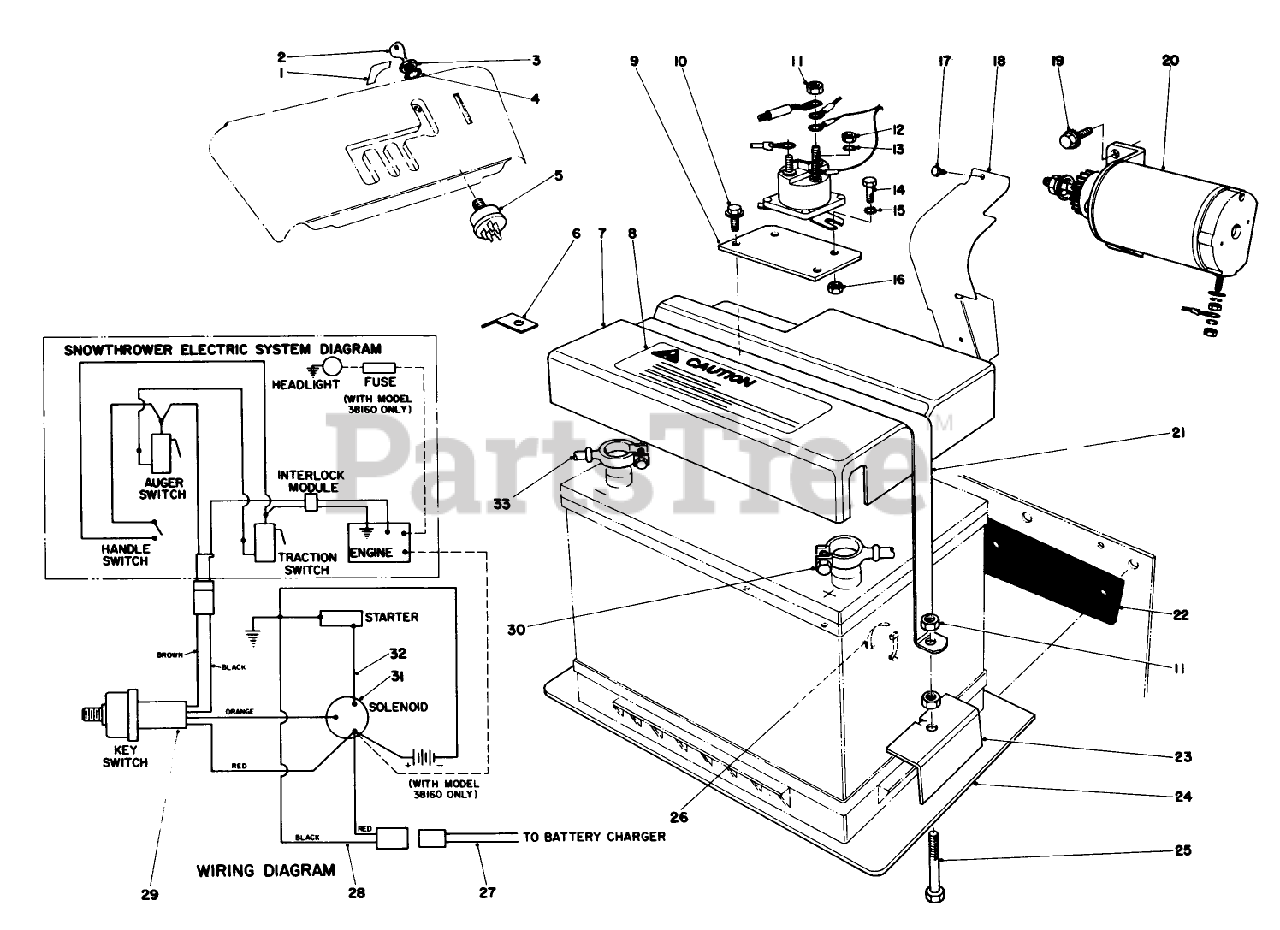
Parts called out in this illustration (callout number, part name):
3	NUT-HH
4	WASHER-LOCK
5	SWITCH-STARTER
10	SCREW-HWH
11	NUT-HEX
12	NUT-HEX
13	WASHER-LOCK, INT
14	SCREW-HH
15	WASHER-LOCK/EXT
16	NUT-LOCK, NI
18	BRIGGS 280265
19	5/16-18X3/4 HX HD SEM
20	Starter Motor Pinion Assy.
25	SCREW-HH
26	TIE-CABLE
27	MALE WIRE ASM
30	BATT-SOLENOID CABLE
31	SOLENOID
